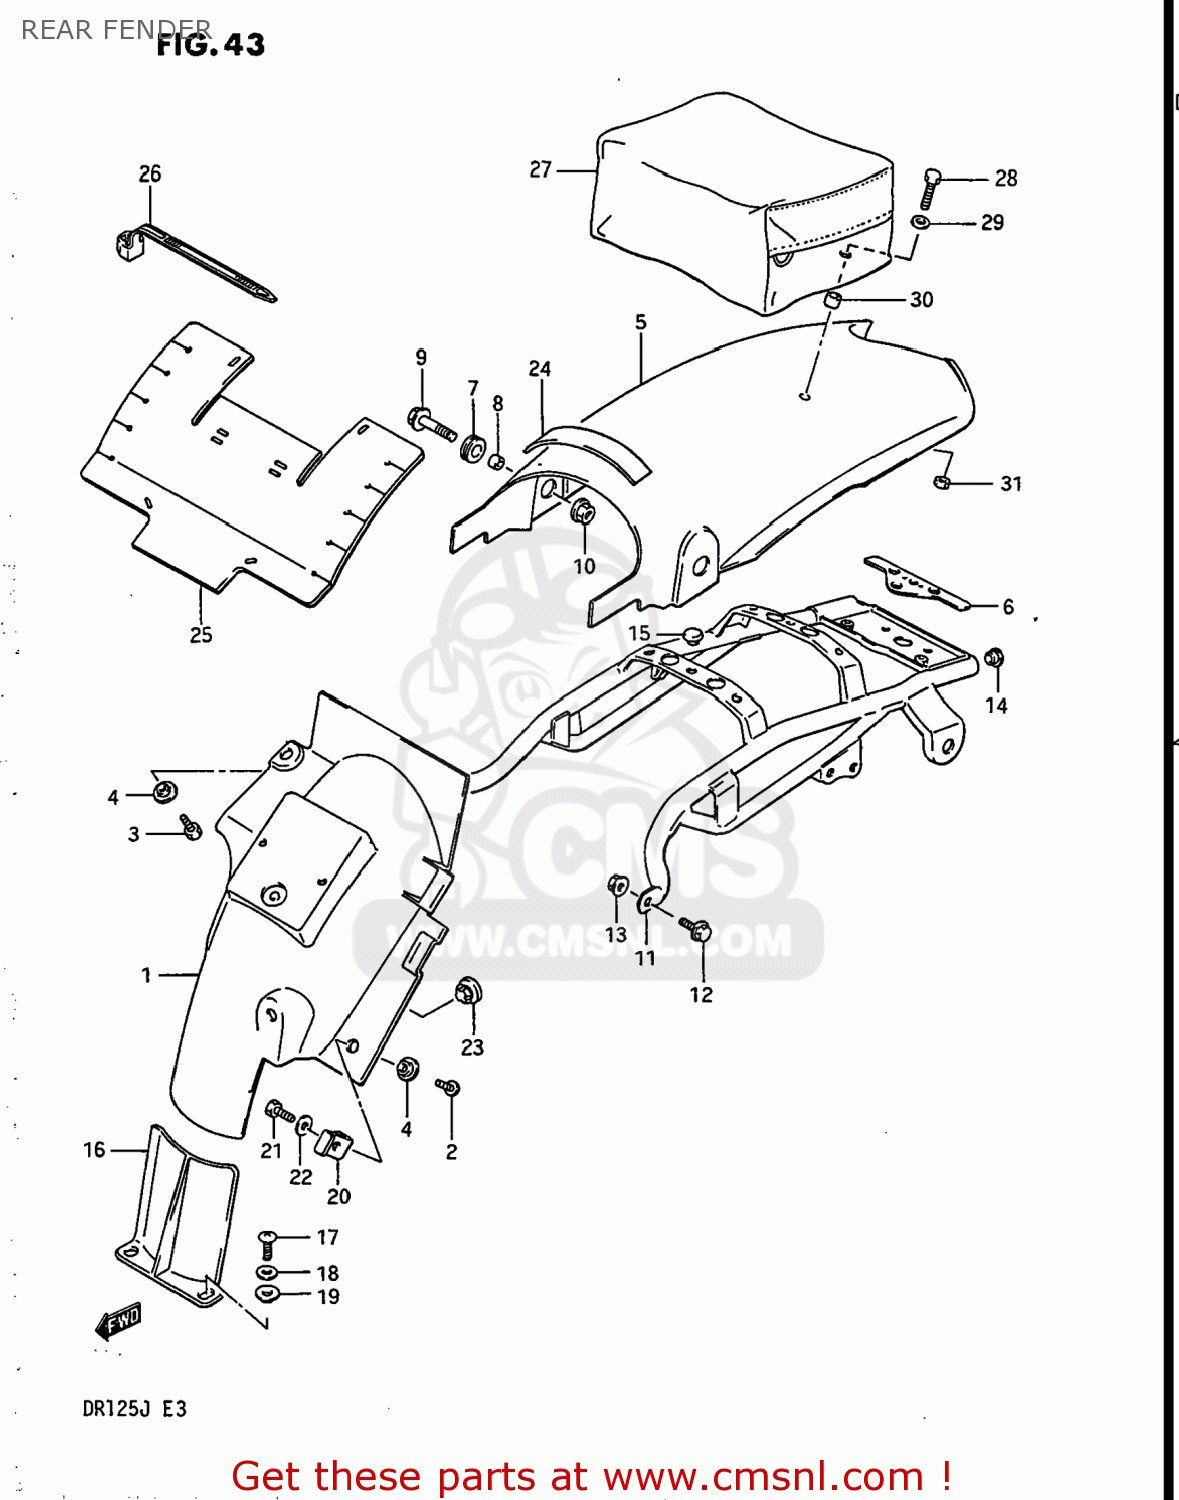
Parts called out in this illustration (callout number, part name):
1	BODY,RR FENDER FR
2	SCREW 6X12
3	BOLT 6X16
4	WASHER
5	FENDER,REAR
6	CUSHION,RR FENDER
7	CUSHION
8	SPACER (8.2X12X7.5)
9	BOLT
10	NUT
11	REINFORCEMENT,REAR FENDER
12	BOLT
13	NUT
14	PLUG
15	CUSHION
16	GUARD,RR UNIT MUD
17	SCREW
18	WASHER(6.5X16X1.2)
19	WASHER,LOCK
20	BRACKET,FENDER LOWER,LEFT
21	BOLT
22	WASHER (6.5X20X1.2)
23	CAP(OD:16)
24	CUSHION(25X185X15)
25	FLAP,AIR CLEANER MUD
26	CLAMP(L:125)
27	BAG ASSEMBLY,SEAT TAIL
28	BOLT
29	WASHER
30	SPACER (6.1X9X9)
31	NUT
